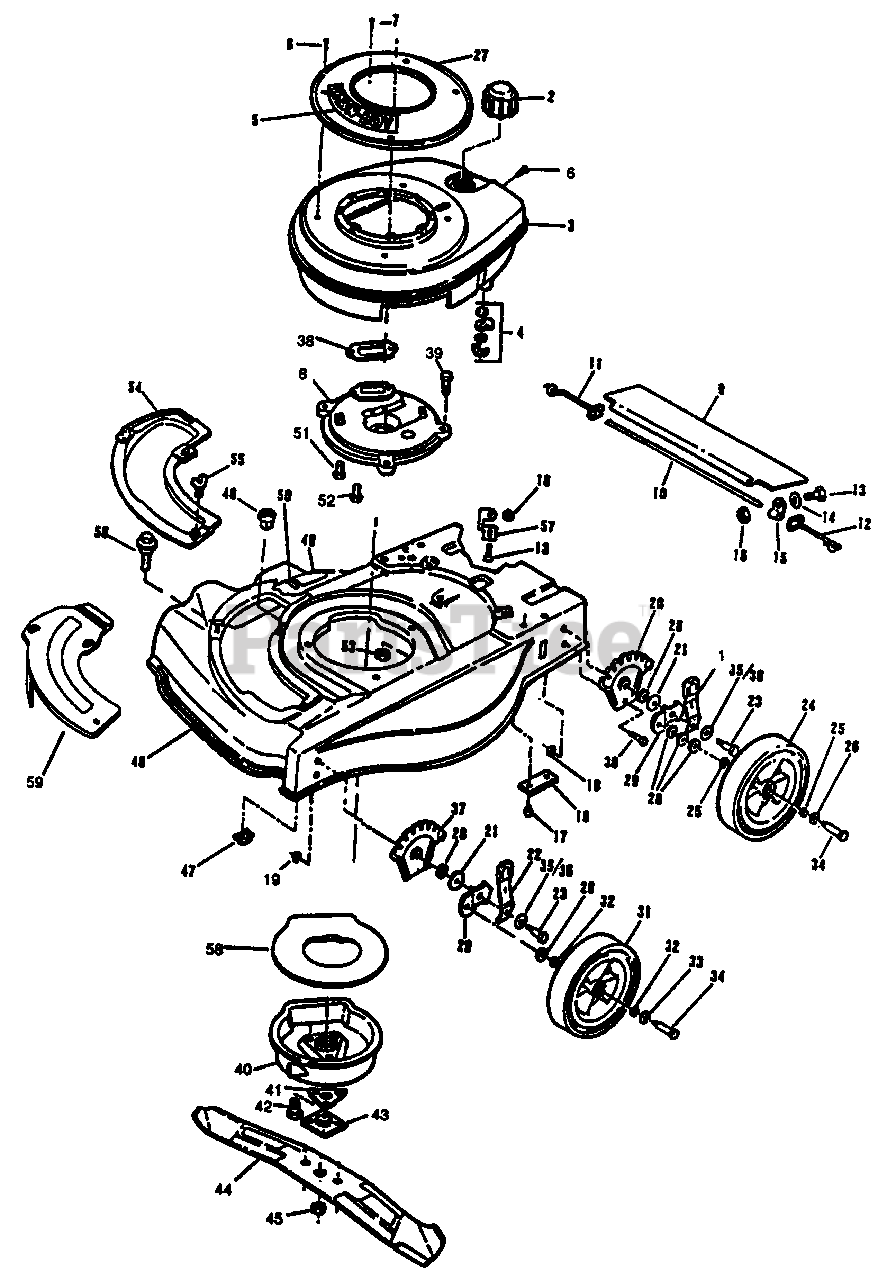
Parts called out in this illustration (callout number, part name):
1	Knob & Spring-Height Adjuster
2	Fuel Cap Assembly
3	Shroud-Engine (Inc. 4)
4	Fuel Shut Off Assembly
5	Applique-Starter Base
6	Screw-Shroud
7	Screw-Starter Mounting
8	Plate-Muffler
9	Shield-Trailing
10	Rod-Trailing Shield
11	Spring-R.H.
12	Spring-L.H.
13	Screw-Trailing Shield
14	Washer-Trailing Shield
15	Clamp-Trailing Shield
16	Nut, Hex Lock
17	Screw-Handle Bracket
18	Plate-Handle Bracket to Hsg
19	Nut-Height Adjust & Back-up Pit
20	Height Adjust Plate-Rear
21	Washer-Wheel Mounting Brkt
22	Knob & Spring-Height Adjust
23	Bolt-Shoulder
24	Rear Wheel
25	Washer-Felt
26	Washer-Flat
27	Starter Base & Nut Assembly
28	Washer
29	Bracket-Wheel Height Adjust
30	Screw-Height Adjust Plate
31	Front Wheel Kit
32	Washer-Felt
33	Washer-Flat
34	Bolt, Shoulder-Wheel Mount
35	Washer-Shim (.010)
36	Washer-Shim (.015)
37	Height Adjust Plate-Front
38	Gasket
39	Screw-Muffler Plate to Housing
40	Muffler Cover
41	Crankshaft Support
42	Screw-Crankshaft Support
43	Collar & Plate Assembly
44	Blade-21"
45	Nut-Blade
46	Housing Assembly (Inc. 47-50)
47	Caged Nut
48	Grommet
49	Decal-Blade Contact Warning
50	Decal-Discharge Area
51	Screw-Muffler Plate to Block
52	Screw-Muffler Plate to Block
53	Nut-Muffler Plate to Housing
54	Cover Plate
55	Wing Screw
56	Screw-Plate & Chute Mounting
57	Baffle Bracket
58	Baffle-Muffler
59	Mulch Plate Accessory
